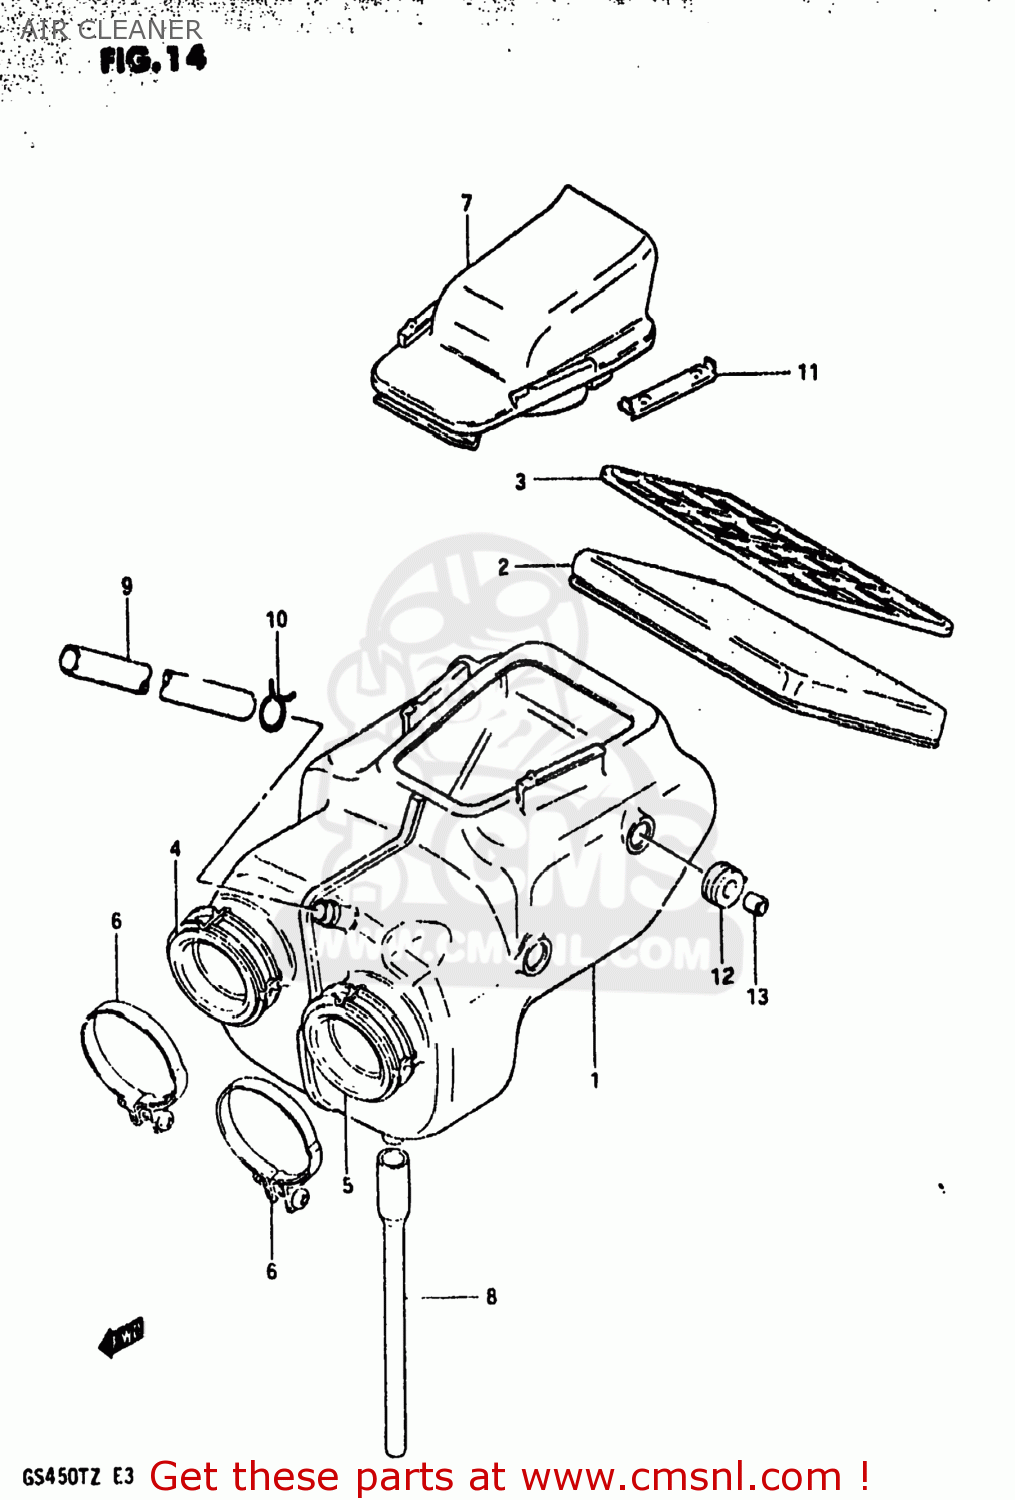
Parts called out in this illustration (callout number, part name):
1	CLEANER ASSEMBLY,AIR
2	FILTER
3	HOLDER NO.2
4	OUTLET,R
5	OUTLET,L
6	CLAMP
7	CAP
8	DRAIN TUBE
9	HOSE
10	CLAMP
11	SLIDER
12	CUSHION
13	SPACER(6.1X9X7.5)
